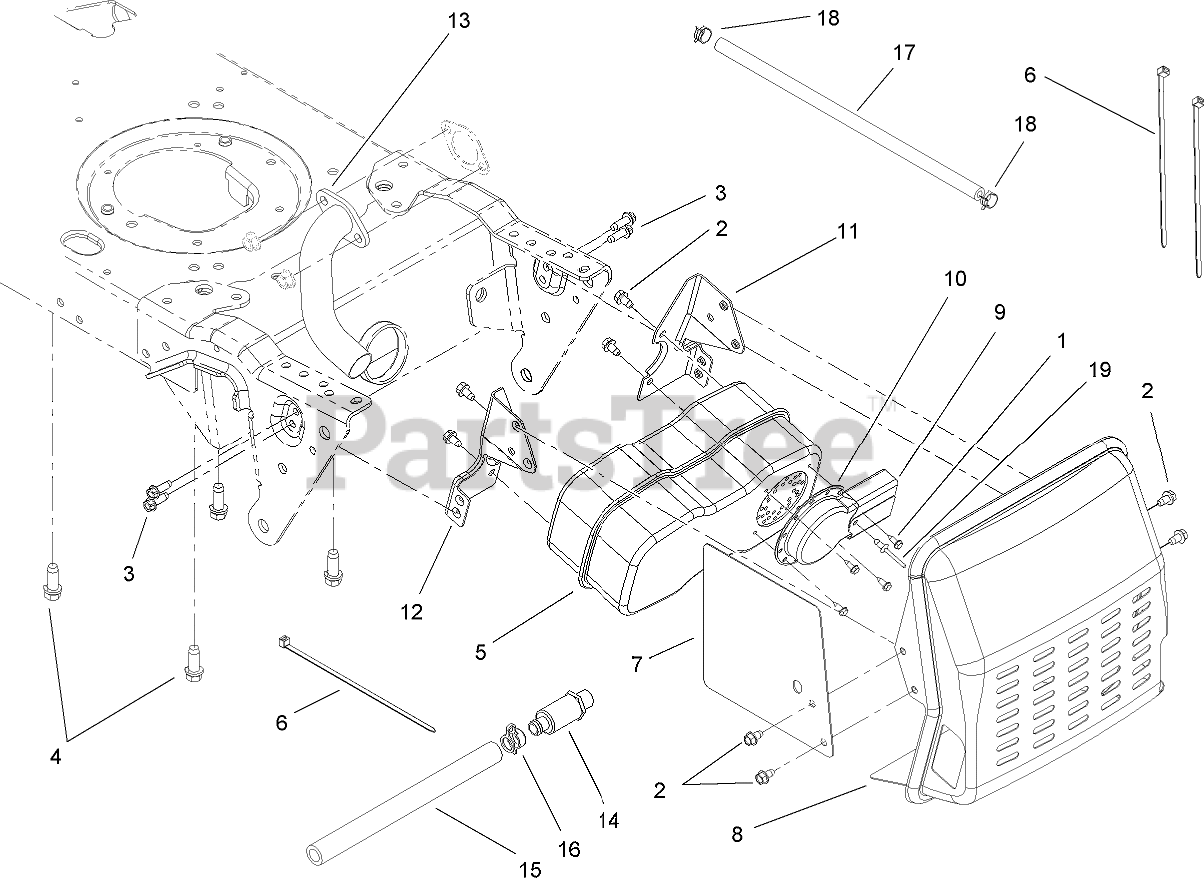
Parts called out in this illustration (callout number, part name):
1	SCREW-HWHTF
2	SCREW-HWHTF
3	SCREW-TAP
4	SCREW-TAP
5	MUFFLER-INLET, SINGLE
6	TIE-CABLE
7	SHIELD-HEAT
8	MUFFLER SHIELD ASM
9	DEFLECTOR-MUFFLER, LONG
10	DEFLECTOR-MUFFLER
11	BRACKET-MUFFLER, LH
12	BRACKET-MUFFLER, RH
13	PIPE-EXHAUST
14	DRAIN-OIL
15	HOSE-DRAIN
16	CAP-DRAIN, OIL
17	HOSE-FUEL
18	CLAMP-HOSE
19	RIVET-POP
